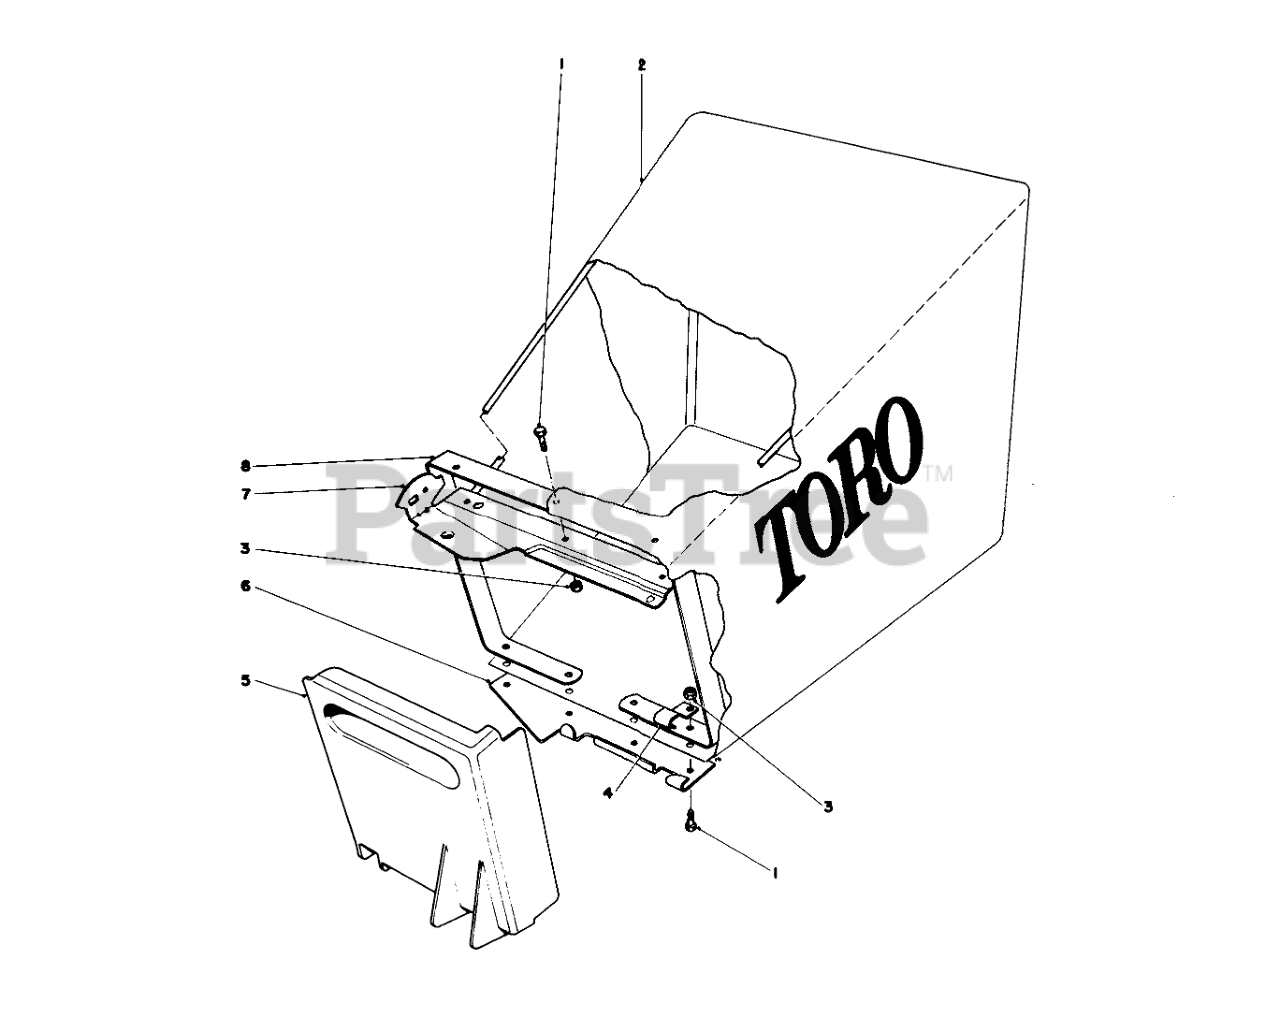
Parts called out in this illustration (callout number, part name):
1	SCREW-HWH
2	REPLACMNT BAG 44-0530
3	NUT/WASHER
4	SUPPORT BRACKET
5	BAG DOOR
6	DOOR BRACKET
7	BAG FRAME WA
8	LOWER BAG FRAME
